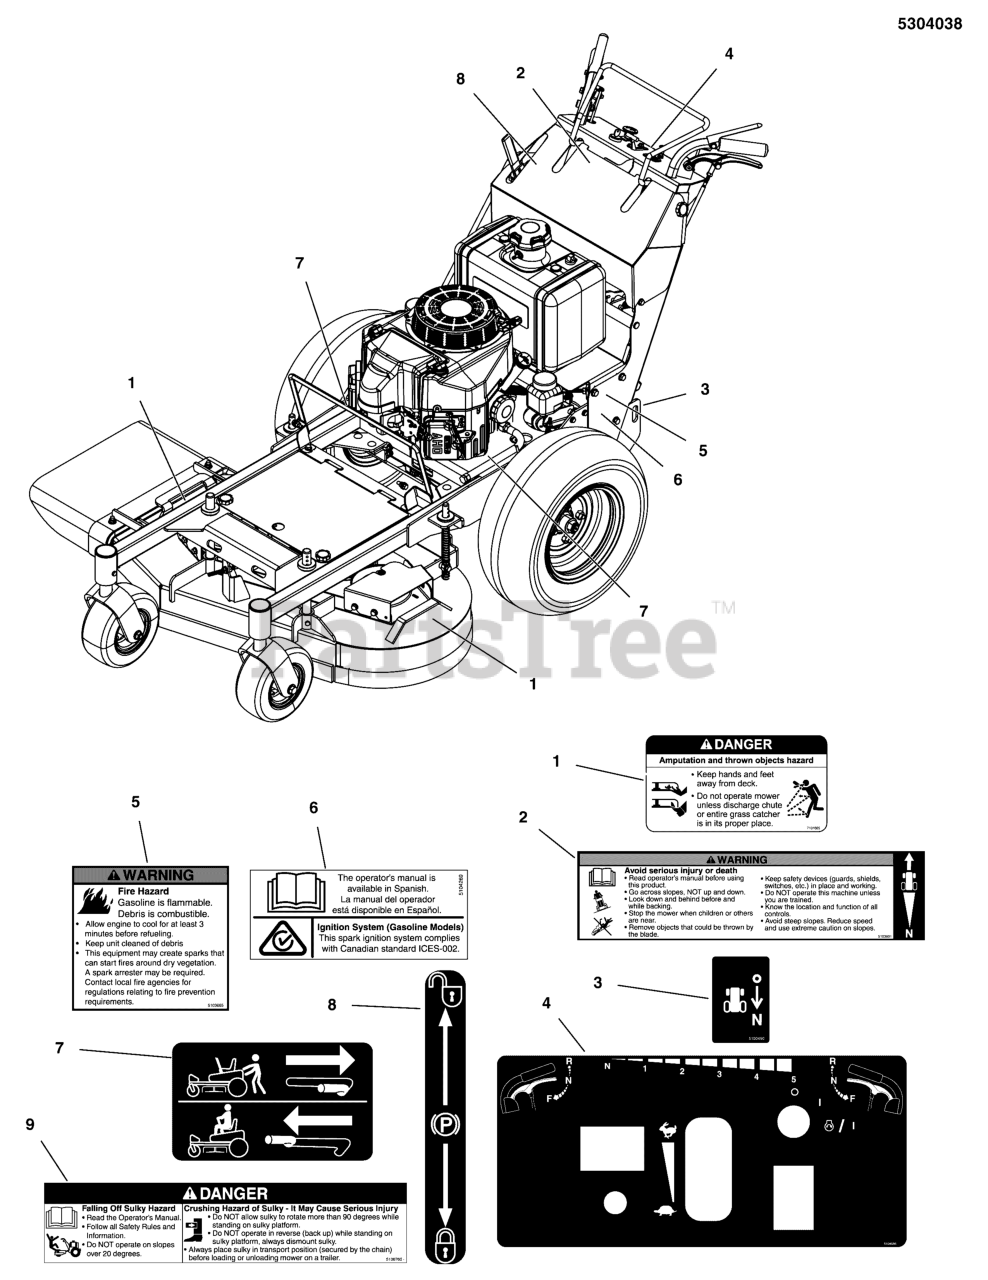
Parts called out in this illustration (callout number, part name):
1	DECAL, DANGER DO NOT OPERATE W/O DEFLECT
2	DECAL, WARNING, WALKS
3	DECAL, PEDAL
4	DECAL, DASH PANEL, WKB, MAN/ELEC START
5	DECAL, FIRE HARARD, 3.25W X 3.0H
6	DECAL, SPANISH MANUAL, IGES, C-TICK
7	DECAL, TRANSAXLE RELEASE, WB
8	DECAL, PARKING BRAKE SYMBOLS
9	DECAL, MAIN SAFETY, SULKY
